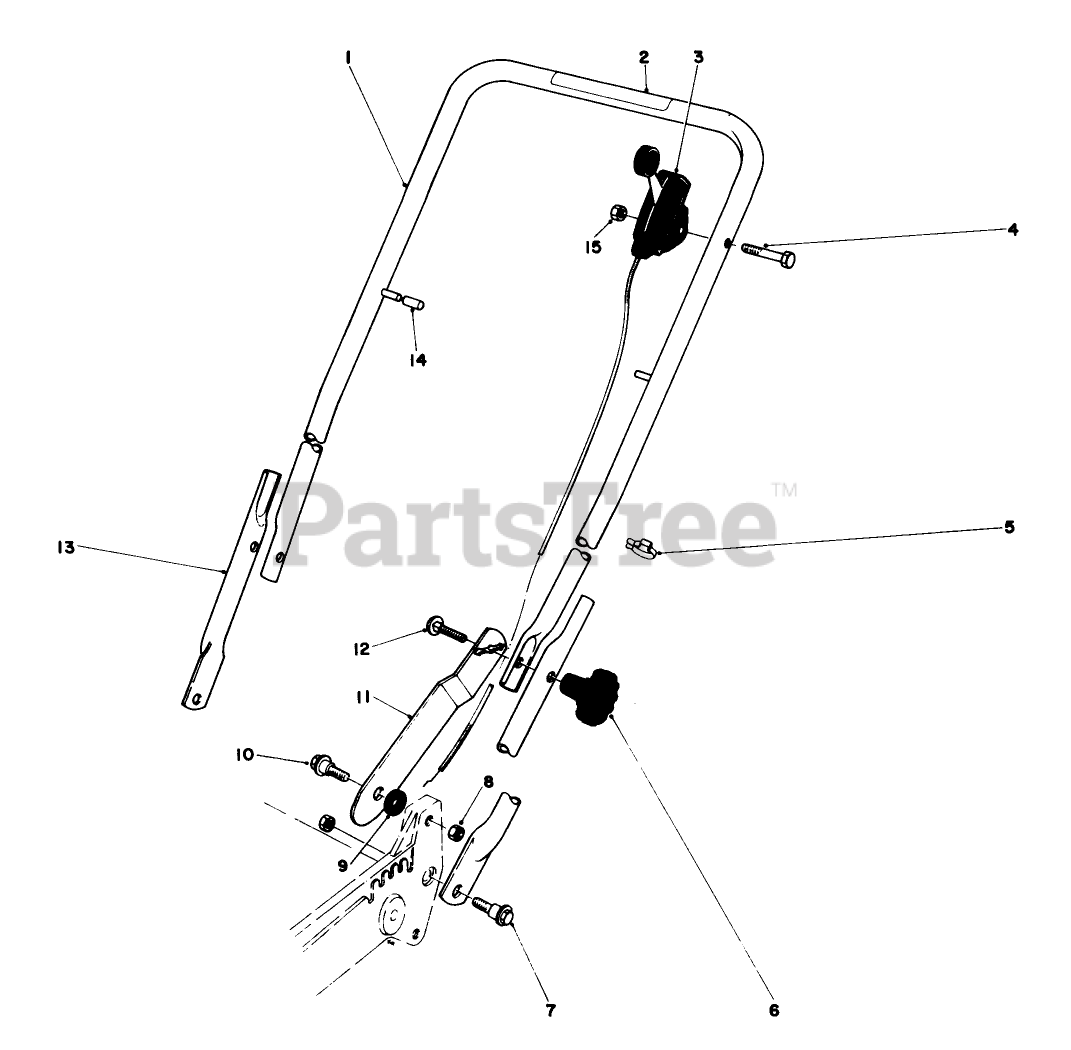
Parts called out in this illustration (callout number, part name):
4	SCREW-HH
5	BOWDEN CLIP
7	SCREW-SHOULDER
9	SPACER
12	BOLT-CAR
